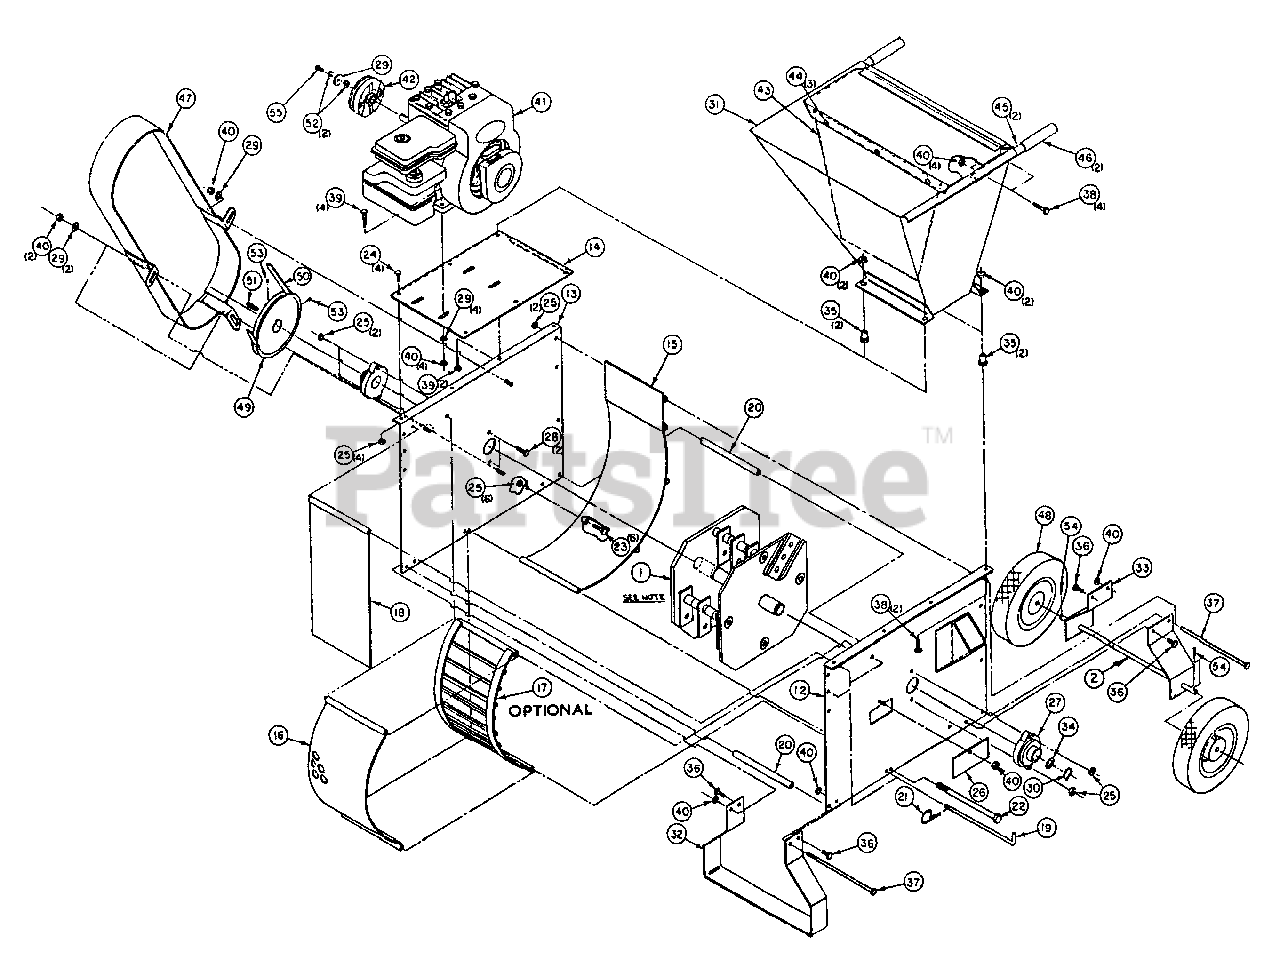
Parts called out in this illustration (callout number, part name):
1	Rotor Weldment
12	Chipper Side Plate
13	Drive Side Plate
14	Top Plate
15	Scroll
16	Screen 1"
17	Bar Screen
18	Baffle Plate
19	Screen & Baffle Rod
20	Pipe Spacer
21	Hair Cotter - 3/32"
22	5/16-18 x 8 Hex Hd. Cap Screw Blk.
23	5/16-18 x 1-1/4 Hex Hd. Cap Screw
24	5/16-1B x 3/4 Hex Hd. Cap Screw
25	5/16-18 Grip-Co Lock Nut
26	Cover Plate
27	Bearing
28	5/16-18 x 1 Hex Hd. Cap Screw
29	5/16 Flatwasher
30	1" Retaining Ring
31	Hopper
32	Front Foot
33	Axle Bracket
34	1 1/2" O.D. x 1 1/64" I.D. x .050 Thk. Shim
35	Vibration Dampener
36	5/16-18 x 3/4 Hex Hd. Cap Screw Pltd.
37	5/16-18 x 8 Hex Hd. Cap Screw Pltd.
38	5/16-18 x 1-1/4 Hex Hd. Cap Screw Pltd.
39	5/16-18 x 1-1/2 Hex Hd. Cap Screw Pltd.
40	5/16-18 Grip-Co Lock Nut Pltd.
41	* ENGINE, 5 HP
42	Clutch
43	Hopper Flex Guard
44	Push Type Tie Button
45	Handle
46	Handle Grip
47	Belt Guard
48	8 x 1.75 Wheel
49	Sheave A550 x 1"
50	V-Belt 4L-410
51	1/4" Sq. x 1" LG Shaft Key
52	5/16 Split Lockwasher
53	5/16-18 x 5/16 Set Screw
54	1/8 x 1-1/4 LG Cotter Pin
55	5/16-24 x 3/4" Hex Hd. Cap Screw
